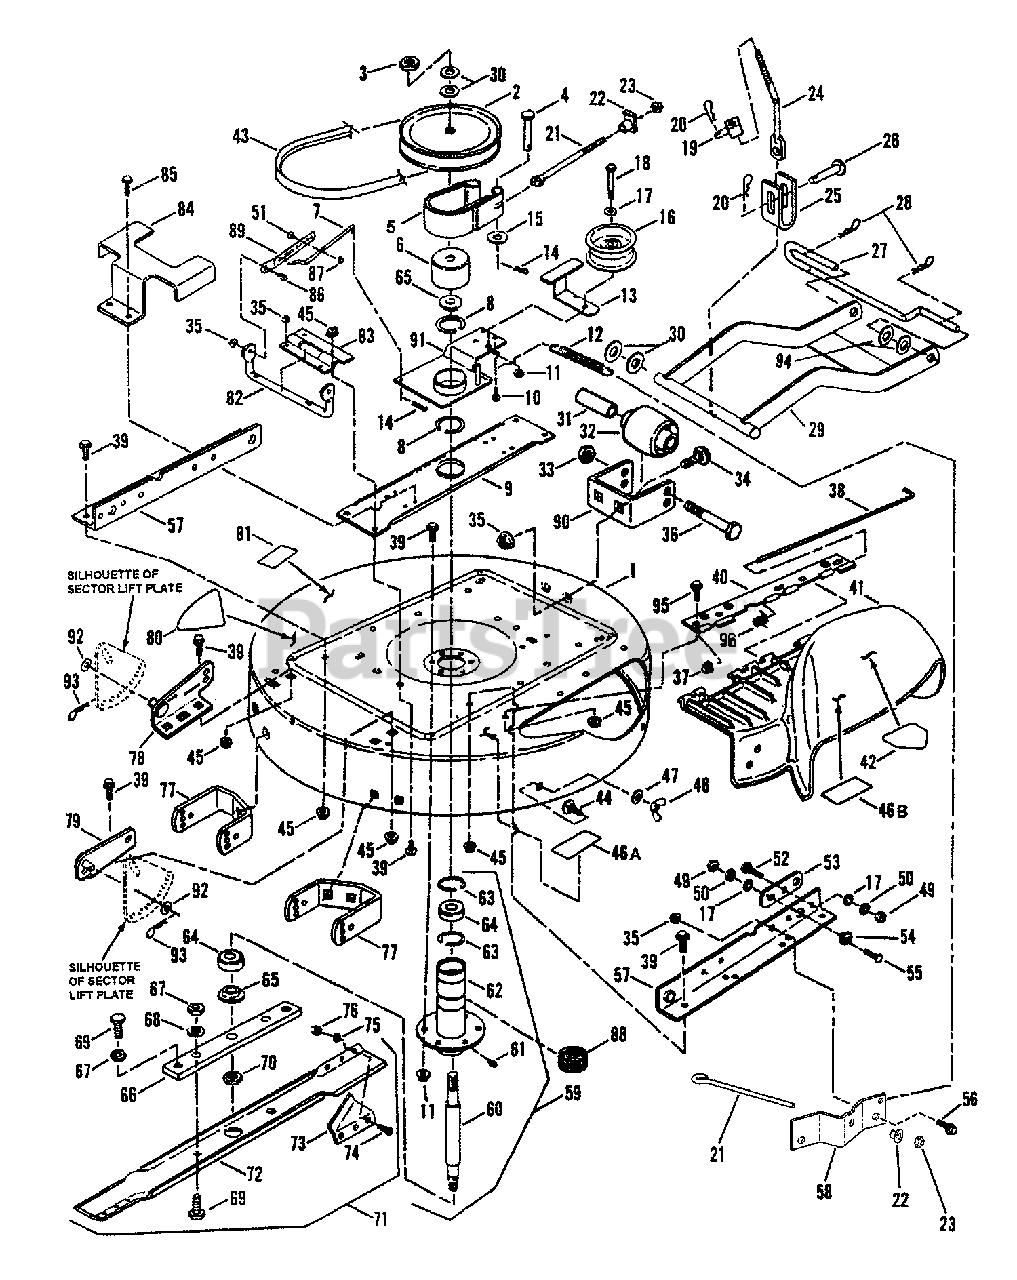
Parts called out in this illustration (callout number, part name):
1	ASSEMBLY, 33" Deck (Includes items 46A & 81)
1	ASSEMBLY, 33" Deck
2	PULLEY, Spindle, 7" O.D.
3	NUT, 3/4-16 Hex Flange Jam, GR8
4	PIN, 1/4 x 1-1/4" Clevis
5	ASSEMBLY, Brake Band
6	DRUM, Brake
7	ROD, Link, Clutch/Brake
8	RING, 2" External Retaining
9	BRACE, Spindle
10	SCREW, 5/16-18 x 3/4" Hex Washer Self-Tap
11	NUT, 3/8-16 Hex Center Lock, GR 5 or B
12	SPRING, Clutch & Brake
13	GUIDE, Belt (Series "H")
13	GUIDE, Belt (Series "I")
14	PIN, 3/32 x 3/4" Cotter
15	WASHER, 1/4" I.D. x 5/8" O.D. Flat
16	IDLER, Flat (4.00 O.D.)
17	WASHER, 3/8" Flat SAE
18	SCREW, 3/8-16 x 1-3/4" Hex Head Cap, GR 5
19	SWIVEL, Brake
20	PIN, 1/4 x 1-1/8" Hair
21	BOLT, 1/4-20 Eye
22	NUT, 1/4-20 Tee
23	NUT, 1/4-20 Hex, GR 5
24	ROD, Front Lift
25	BRACKET, Front Lift Hanger
26	PIN, 3/8 x 1-1/2" Clevis
27	PIN, Deck Hanger Improved
28	HAIRPIN, .148 x 2.62
29	WELDMENT, Front Lift Arm
30	WASHER, 3/4" I.D. Flat
31	SPACER
32	WHEEL, Gage
33	NUT, 3/8-24 Hex Center Lock, GR 5
34	BOLT, 5/16-18 x 1/2" Short Neck Carriage, GR 5
35	NUT, 5/16-18 Hex Flange Lock, GR 5
36	SCREW, 3/8-24 x 3-3/4" Hex Head Cap, GR 5
37	PALNUT, 1/4" Hex
38	PIN, Hinge
39	BOLT, 3/8-16 x 3/4" Hex Flange Lock
40	HINGE, Deflector
41	ASSEMBLY, Deflector (Includes items 37, 38, 40, 41, 42 & 96)
41	ASSEMBLY, Deflector- Euro
41	DEFLECTOR, Discharge
42	DECAL, Danger, Cut Finger
43	BELT, HA Section, 56.25" effective length
43	BELT, HA Section, 56.95" effective length
44	BOLT, 5/16-18 x 3/4" Short Neck Carriage, GR 5
45	NUT, 3/8-16 Hex Flange Lock
46A	DECAL, Caution, Deflector
46B	DECAL, Caution, Deflector
47	WASHER, 5/16" Flat
48	NUT, 5/16-18 Wing
49	NUT, 3/8-16 Hex
50	WASHER, 3/8" Split Lock
51	BOLT, 1/4-20 x 1/2" Hex Flange Lock, GR 5
52	BOLT, 3/8-16 x 3/4" Short Neck Carriage, GR 5
53	ADJUSTMENT & LINK
54	ADJUSTMENT RING
55	SCREW, 3/8-16 x 1" Hex Head Cap, GR 5
56	BOLT, 5/16-18 x 1/2" Flange Lock, GR 5
57	RAIL, Side
58	ANCHOR, Brake
59	ASSEMBLY, Spindle (Includes items 60 thru 70)
60	SPINDLE, 4" Shoulder
61	LUBE FITTING, Straight (press-fit for .187 dia. Hole)
62	WELDMENT, Spindle Housing (Includes item 61)
63	RING, 1-3/4" Retaining
64	BALL BEARING, 3/4" I.D.
65	WASHER, Spindle
66	HOLDER, Blade
67	NUT, 1/2-20 Hex Jam
68	WASHER, 1/2" Internal Tooth Lock
69	SCREW, 1/2-20 x 1-1/4" Hex Head Cap, GR 5
70	NUT, 5/8-18 Hex Center Lock Jam, GR 5 or B
71	ASSEMBLY, Blade & Air Lift
72	BLADE, 33" Cutting Deck (Euro)
73	AIR-LIFT
74	SCREW, 5/16-24 x 11/16" Machine
75	WASHER, 5/16" Internal Tooth Lock
76	NUT, 5/16-24 Hex, GR 5
77	BRACKET, Gage Wheel (Rear)
78	BRACKET, Rear Deck Lift, Left Side
79	WELDMENT, Bracket, Sector Lift - RR
80	DECAL, 33" Hi-Vac
81	DECAL, Caution (Rotating Blades)
82	ARM, Pivot
83	BRACKET, Pivot Arm
84	GUIDE, Belt
85	SCREW, 5/16-18 x 5/8" Hex Washer Self-Tap
86	SHOULDER BOLT, 5/16-18
87	NUT, 1/4-20 Hex Flange Lock
88	RING, Tolerance
89	BRACKET, Link, Clutch/Brake
90	BRACKET, Gage Wheel (Front)
91	WELDMENT, Brake Arm
92	WASHER, 3/8" Flat SAE
93	HAIR PIN, 3/32 x 1.5"
94	WASHER, .531 x 1.062 x .121 Flat SAE
95	BOLT, 3/8-16 x 3/4" Hex Flange Lock, GR 5
96	SPRING, Hinge
